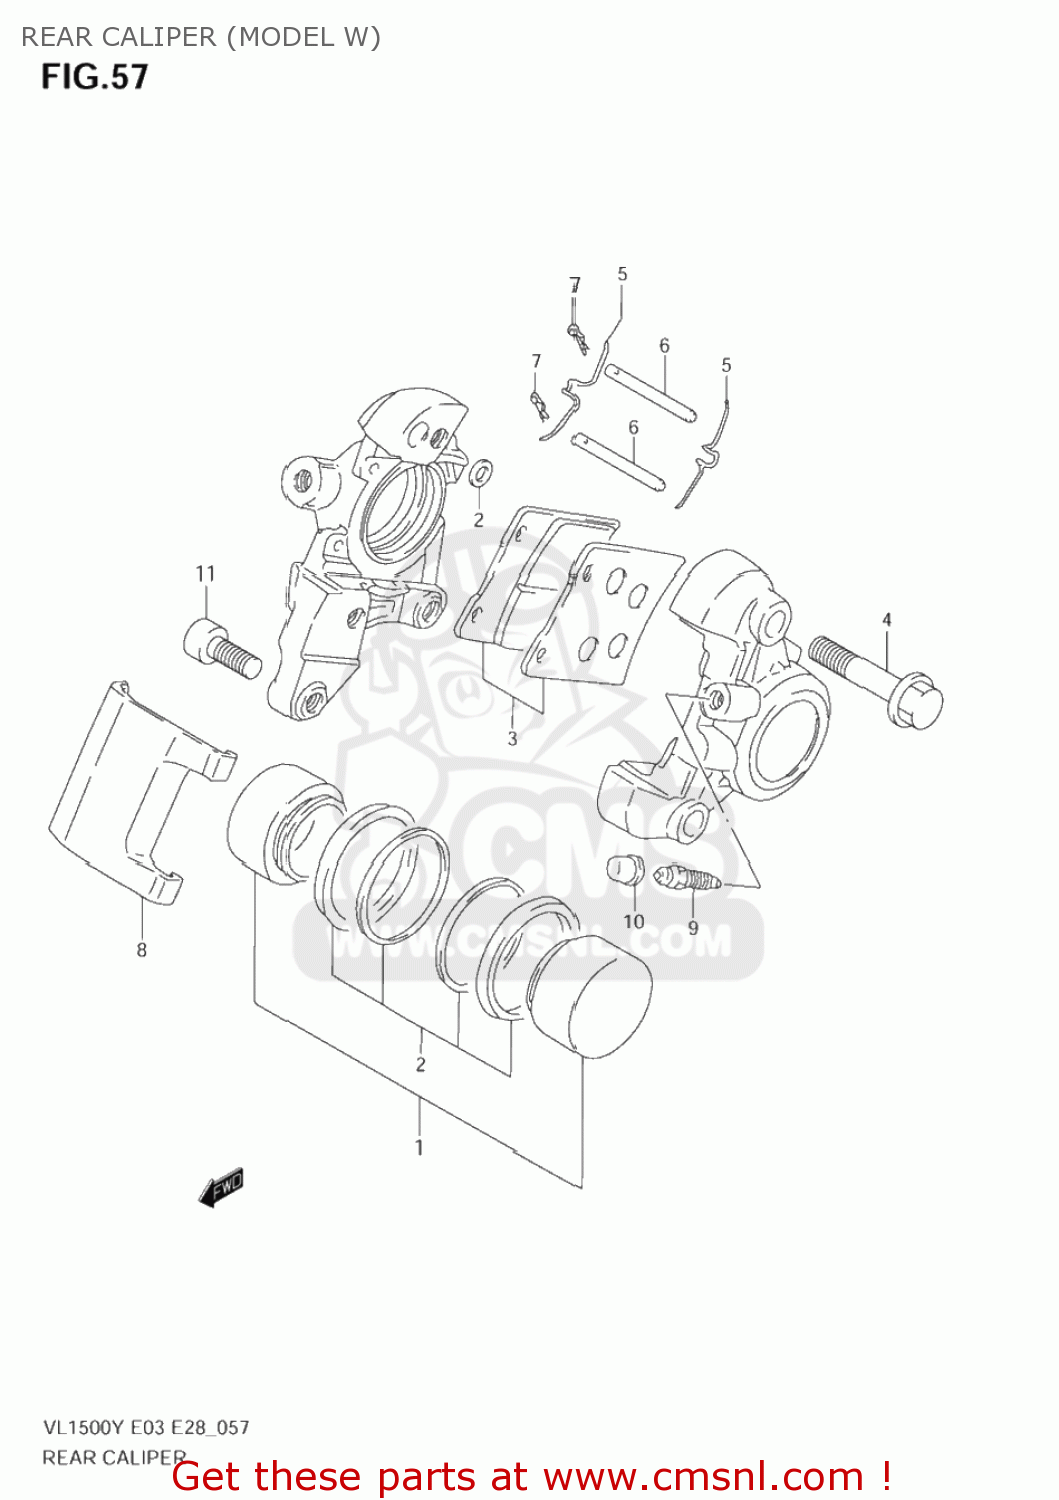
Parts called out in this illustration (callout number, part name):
1	PISTON SET
2	SEAL SET,PISTON
3	PAD SET (NAS)
4	BOLT,HOUSING
5	SPRING
6	PIN,PAD
7	CLIP,PAD PIN
8	COVER
9	BLEEDER
10	CAP,BLEEDER PLUG
11	BOLT
